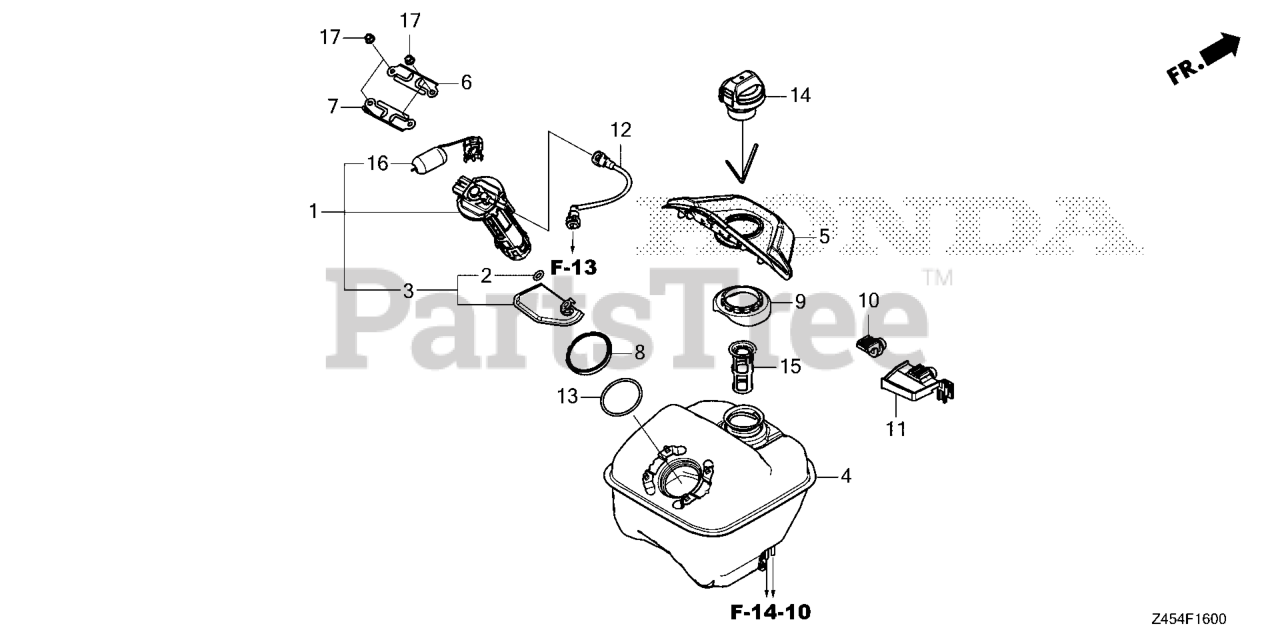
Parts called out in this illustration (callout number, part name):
1	UNIT, FUEL PUMP
2	O-RING (6.8X1.9)
3	FILTER SET
4	TANK COMP, FUEL
6	RETAINER, FUEL PUMP
7	RETAINER, FUEL PUMP
8	DUST SEAL (OHTUKA POLY-TECH)
9	RUBBER, FUEL FILLER
10	RUBBER A, TANK MT
11	RUBBER B, TANK MT
12	HOSE COMP, FUEL FEED
13	O-RING, FUEL PUMP
15	FILTER COMP, FUEL
17	NUT, FLANGE (6MM)
